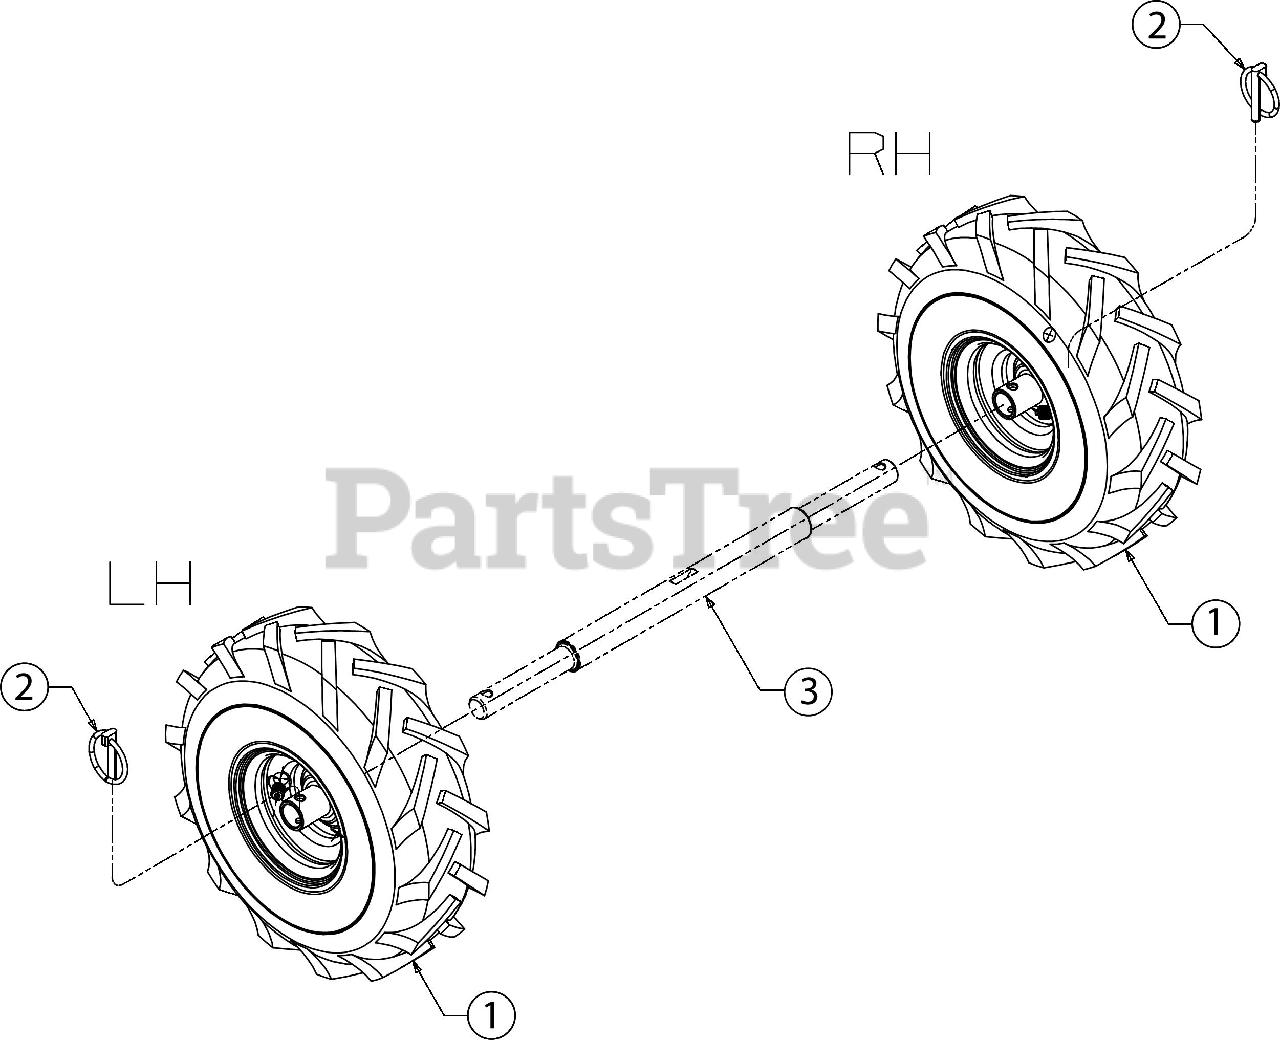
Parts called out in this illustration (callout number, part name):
1	WHEEL ASSEMBLY (11 x 4-4)
1	TUBELESS VALVE
1	TIRE-TILLER AG 11 x 4-4
3	WHEEL SHAFT
